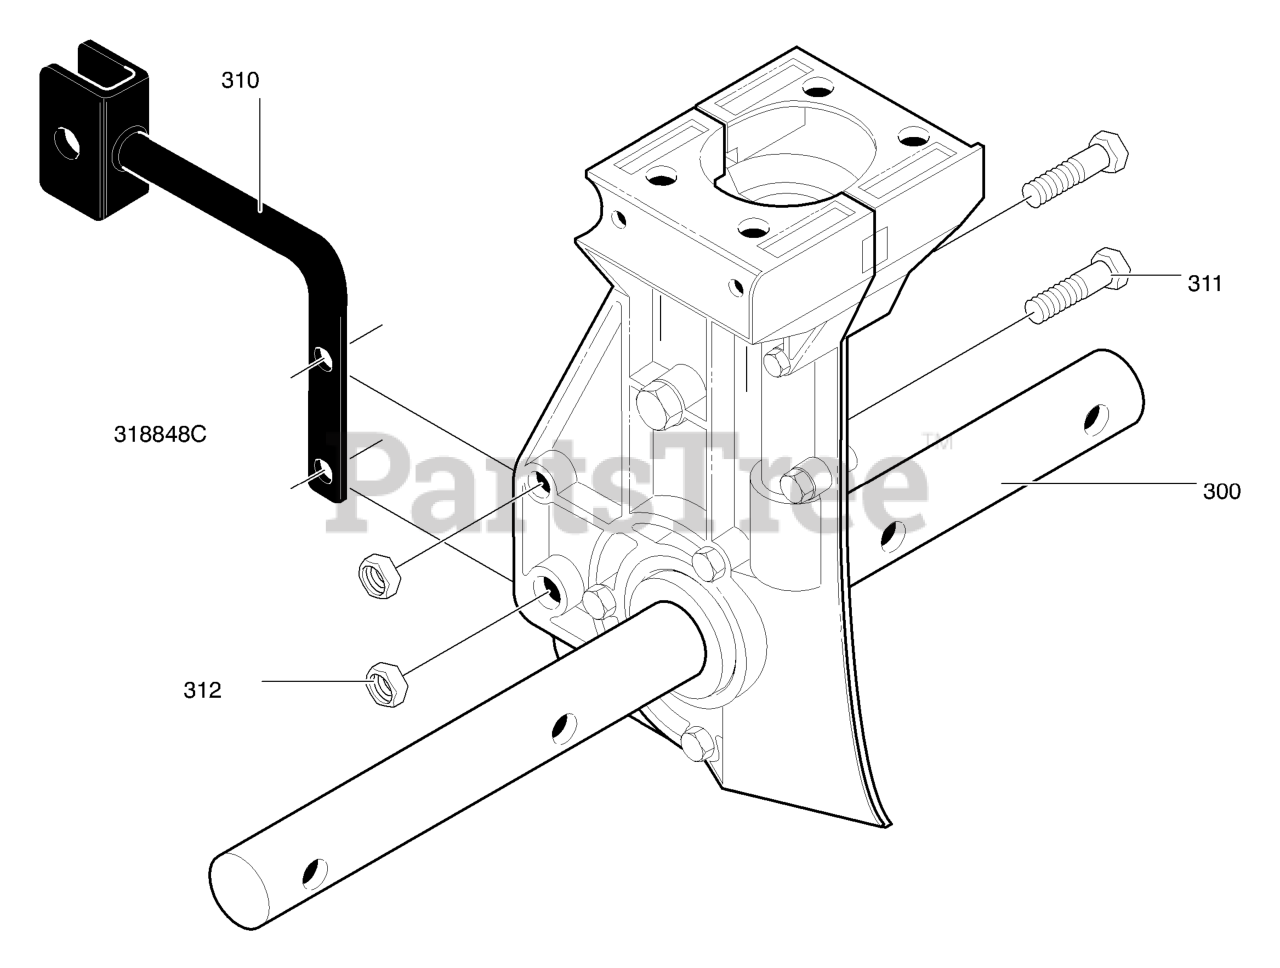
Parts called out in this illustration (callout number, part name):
300	Transmission
310	Bracket, Depth Rod
311	Screw, 1/4-20x1.25
312	Nut, 1/4-20
